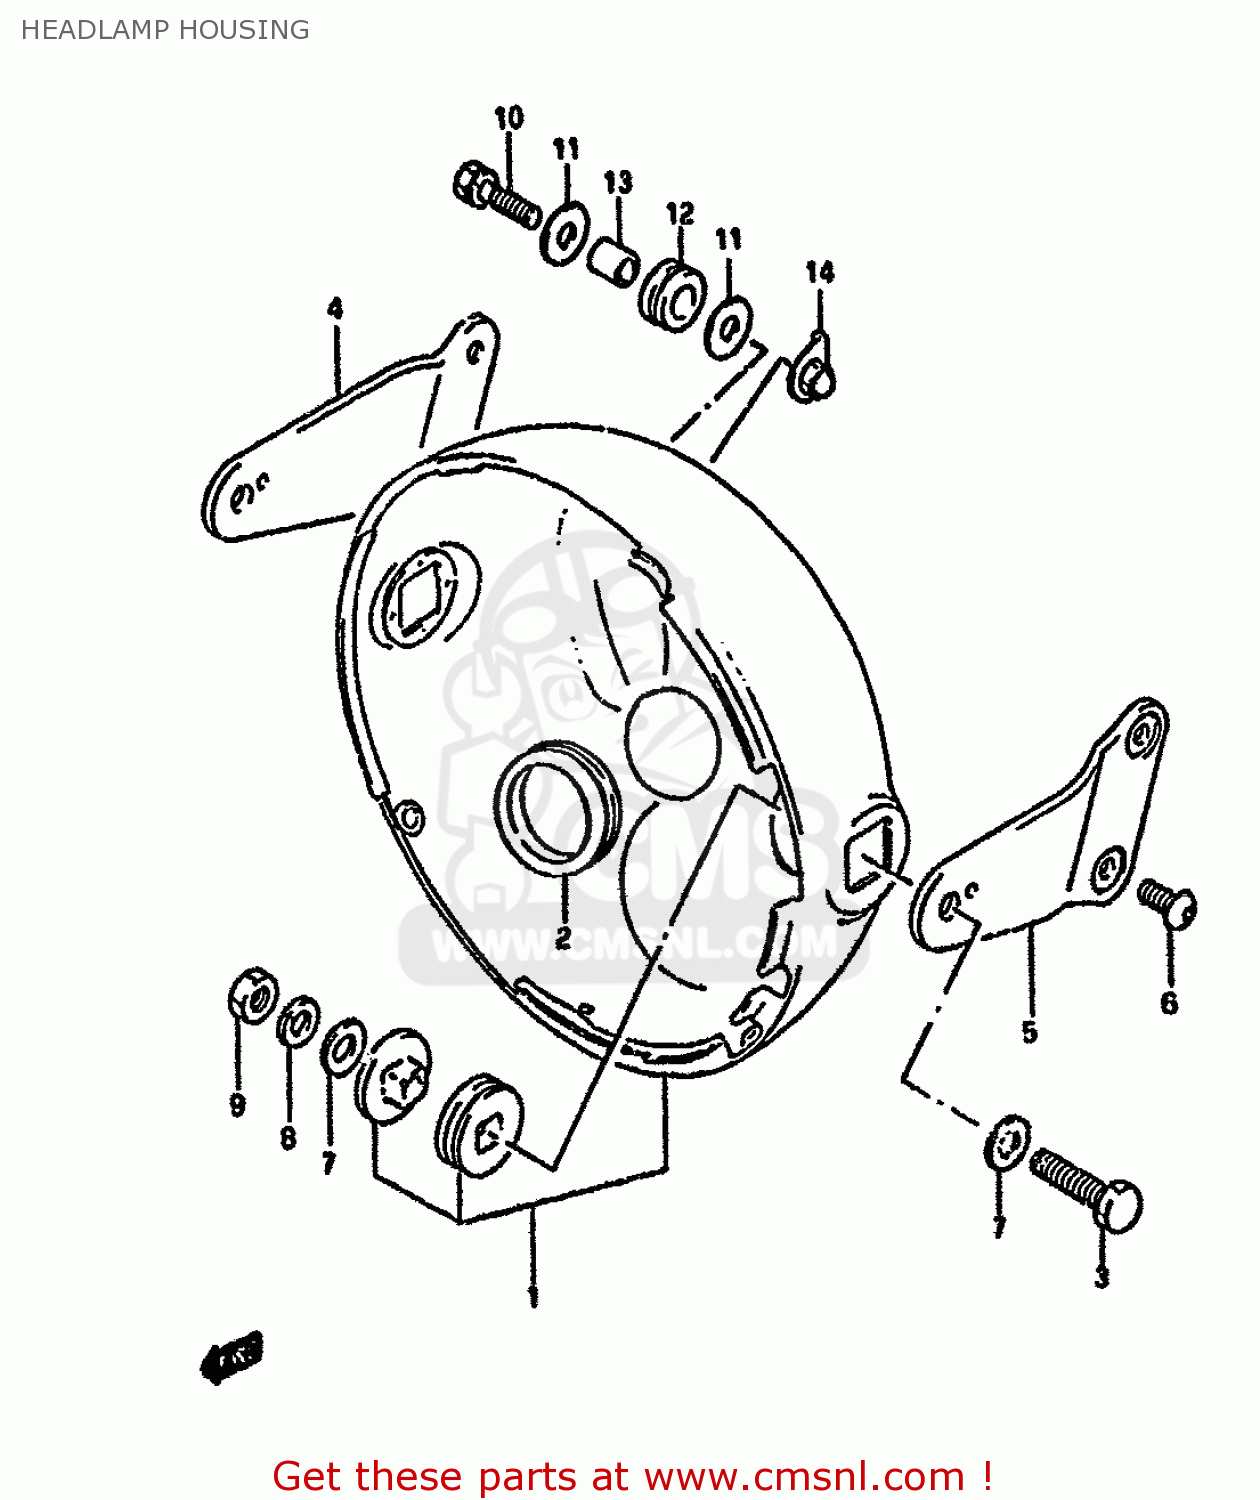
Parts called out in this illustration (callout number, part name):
1	HOUSING,HEADLAMP
2	GROMMET
3	BOLT
4	STAY,HEADLAMP HOUSING,R
5	STAY,HEADLAMP HOUSING,L
6	SCREW(6X12)
7	WASHER
8	LOCK WASHER
9	NUT
10	BOLT
11	WASHER
12	CUSHION
13	SPACER(6.5X10.5X12)
14	PLATE,HEADLAMP
